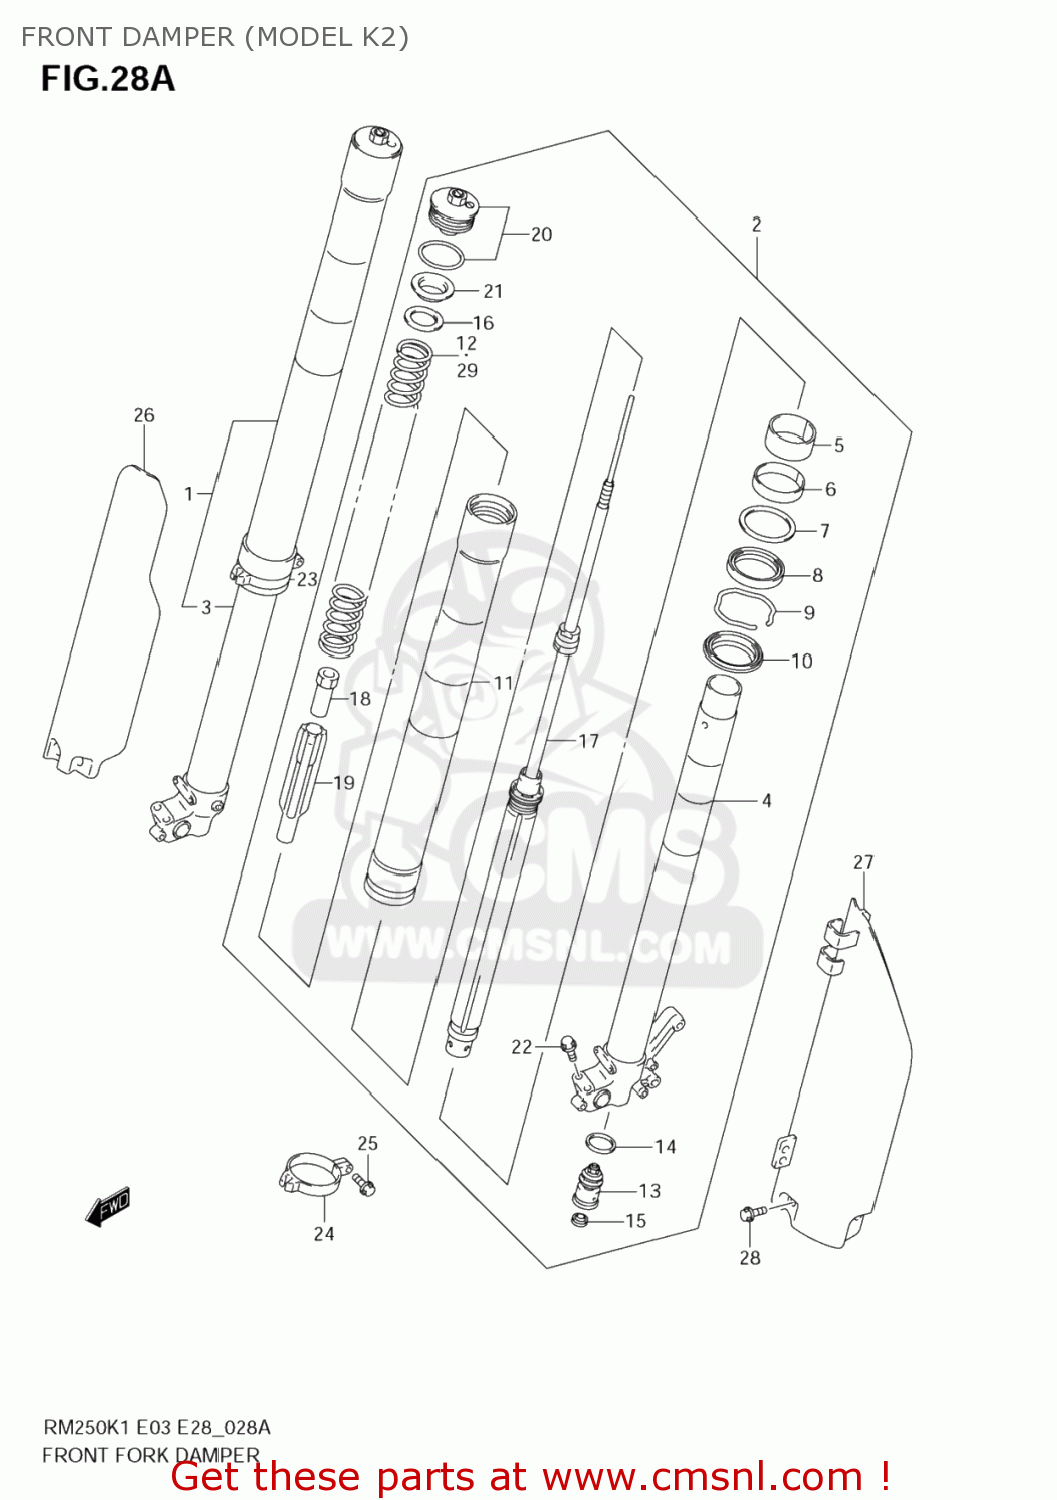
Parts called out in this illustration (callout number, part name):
1	DAMPER ASSY,FR FORK,R
2	DAMPER ASSY, FRONT FORK LH
3	TUBE,INNER,R
4	TUBE,INNER,L
5	BUSH,SLIDE
6	BUSH,GUIDE
7	WASHER
8	SEAL,OIL
9	RING,STOPPER
10	SEAL,DUST
11	TUBE,OUTER
12	SPRING, FRONT
13	VALVE ASSY,BASE
14	PACKING (NAS)
15	CAP,RUBBER
16	WASHER
17	ROD ASSY,PISTON
18	NUT
19	GUIDE,SPRING
20	CAP
21	GUIDE,SPRING
22	BOLT
23	GUIDE,PROTECTOR,R
24	GUIDE,PROTECTOR,L
25	BOLT
26	PROTECTOR FORK,R
27	PROTECTOR,FORK,L
28	BOLT
29	SPRING,FR(HARD) K=0.45
